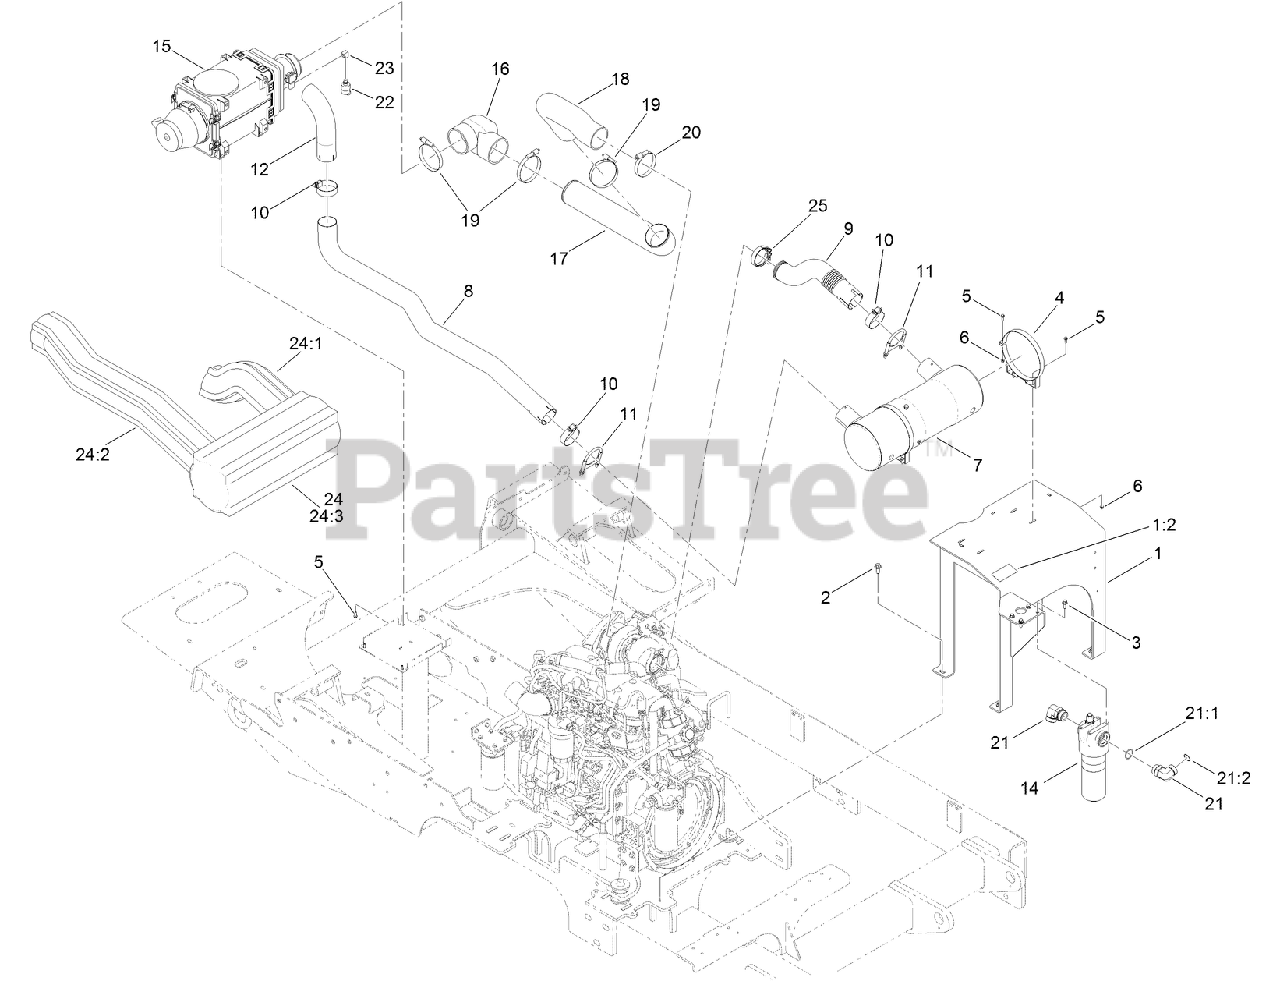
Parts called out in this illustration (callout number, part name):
1	EXHAUST MOUNT ASM
1:2	DECAL-WARNING, HOT SURFACE
2	SCREW-HHF
3	SCREW-HHF
4	BAND-MOUNTING, MUFFLER
5	SCREW-HHF
6	NUT-FLANGE, NI
7	EXHAUST
8	TUBE-EXHAUST, OUT
9	TUBE-EXHAUST, TURBO
10	CLAMP-TORCTITE
11	CLAMP-GUILLOTINE
12	PIPE-STACK
14	FILTER-HYD, HIGH PRESSURE
15	AIR CLEANER ASM
16	ELBOW-INTAKE, AIR CLEANER
17	TUBE-INTAKE, TURBO
18	HOSE-INTAKE, TURBO
19	CLAMP-TORQUE, CONSTANT
20	CLAMP-TORQUE, CONSTANT
21	FITTING-ELBOW 90
21:1	O-RING
21:2	O-RING
22	SWITCH ASM
23	FITTING-ELBOW, 90
24	EXHAUST WRAP ASM
24:1	WRAP-EXHAUST, INLET ELBOW
24:2	WRAP-EXHAUST, OUTLET ELBOW
24:3	WRAP-EXHAUST, MUFFLER
